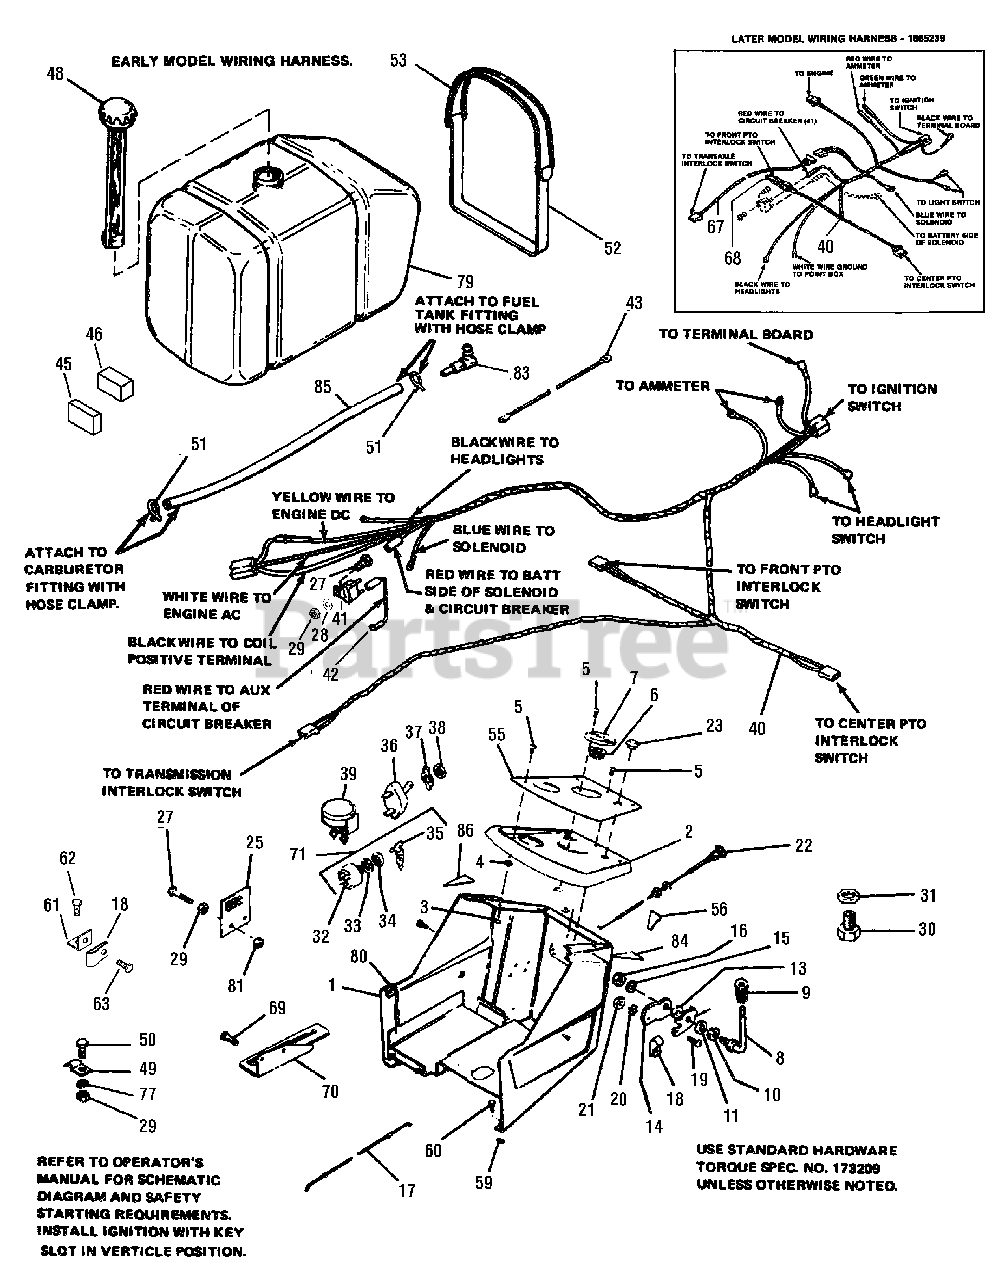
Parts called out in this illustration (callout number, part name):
1	DASH ASSEMBLY
2	PANEL, Instrument
3	NUT, Retainer, Tinn.
4	WASHER, Plain, 3/16
5	SCREW, Mach. Rd. Hd., 1/4-20 x 1/2
7	PLATE STEERING, Adj.
8	HANDLE, Clutch Control
8	HARNESS ASSEMBLY (1690427 Only)
8	HARNESS ASSEMBLY (1690429 Only)
9	KNOB, Tapered
12	STOP, Throttle Kit (inc. ref. 10, 11)
14	ARM, Throttle
15	LOCKWASHER, Dished Shakeproof, 3/8
16	LOCKNUT, Hex, 3/8-16
17	CONTROL, Throttle
18	CLIP, Bowden Wire
19	SCREW, Rd. Hd., No. 10-32 x 1/2
20	LOCKWASHER, External, No. 10
21	NUT, Mach. Hex, No. 10-32
22	CONTROL, Choke
23	PLUG, Button
25	BOARD, Terminal
27	CAPSCREW. Hex Hd, 1/4-20 x 5/8
27	NUT, Lock. Hex, 1/4-20
28	LOCKWASHER, Shakerproof, 1/4
29	NUT, Hex, 1/4-20
30	SWITCH-INTERLOCK Ball Check .656 Lg Thread
30	SCREW, Hex Cap, 1/4-20 x 3/4
31	SCREW, Special
32	SWITCH, Ignition
33	LOCKWASHER, Internal, 5/8
34	NUT, Hex Special
35	KEY & RING ASSEMBLY
36	SWITCH, Toggle
37	PLATE
38	NUT
40	HARNESS ASSEMBLY (1690342 Only)
41	CIRCUIT BREAKER
42	WIRE ASSEMBLY
43	SWITCH, Interlock
44	NUT, Pal
45	QUADRANT
46	PAD, Fuel Tank
47	FITTING, Gas Tank
48	CAP, Fuel Tank
50	TANK ASSY, Fuel, Inc. Ref No's. 47, 49, 51, & 54
51	CLAMP, Hose
52	STRAP, Tank
53	STRAP, Fuel Tank
55	DECAL, Instrument Panel
56	DECAL, Ignition
57	DECAL, Throttle Control
58	DECAL, Hydrostatic Control
59	NUT, Speed, Tinn.
60	SCREW, Hex Hd. Thd. Forming, No. 14 x 3/4
61	BRACKET, Cable
63	NUT-HEX Lock Pal .562-18
64	SWITCH, Key Assy.
65	LOCKWASHER, 1/4
66	CLIP, Cable
67	WIRE ASSY. (Used only with Wiring Harness No. 1665239)
68	WIRE ASSY. (Used only w/Wiring Harness No. 1665231)
80	CLIP, Wire
